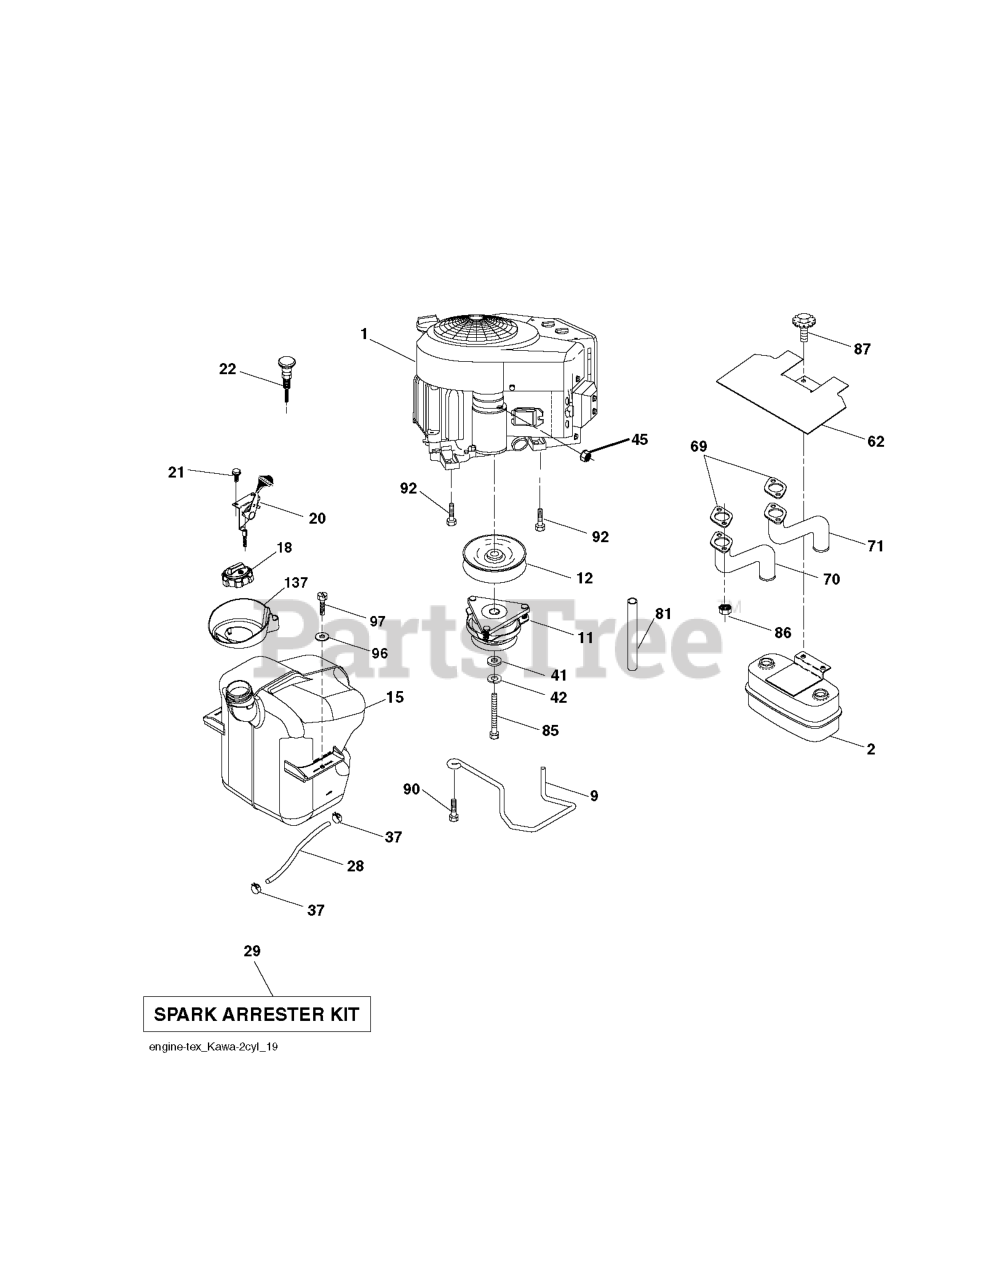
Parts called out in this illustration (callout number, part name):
2	MUFFLER.TWIN.CYL.LOW.TONE
9	KEEPER.BELT.ENGINE.4.2
11	RB.CLUTCH.OGURA.4.4.PD
12	PULLEY.ENGINE.TUFFTORQ
15	FUEL TANK TANK. ASSEMBLY. EXTE
18	CAP.ASM.FUEL.2.25"TOP.TURN
20	CONTROL.THROTTLE.COBRA.BLACK
21	SCREW.#10 X 0.750.BOS
22	CONTROL.CHOKE.ERGO.PUSH-IN.BLA
28	LINE.FUEL.20
29	KIT.SPARK ARRESTOR 794945 B&S
37	HOSE CLAMP
42	LOCKWASHER
45	NUT
62	SHIELD.HEAT.MUFFLER
70	TUBE.EXHAUST.LH.FR961/FR730
71	TUBE.EXHAUST.RH.FR961/FR730
81	TUBE, DRAIN OIL ASM.
85	BOLT HEX 7/16-20X4-1/4"
86	NUT.HEX.FLANGE.TOPLOCK
87	BOLT.5/16-18UNCX3/4 W/SEMS.BLK
90	SCREW 3/8-16X1
92	SCREW 3/8-16X1
96	WASHER
97	SCREW HEXWSHR 1/4-20X3/4
